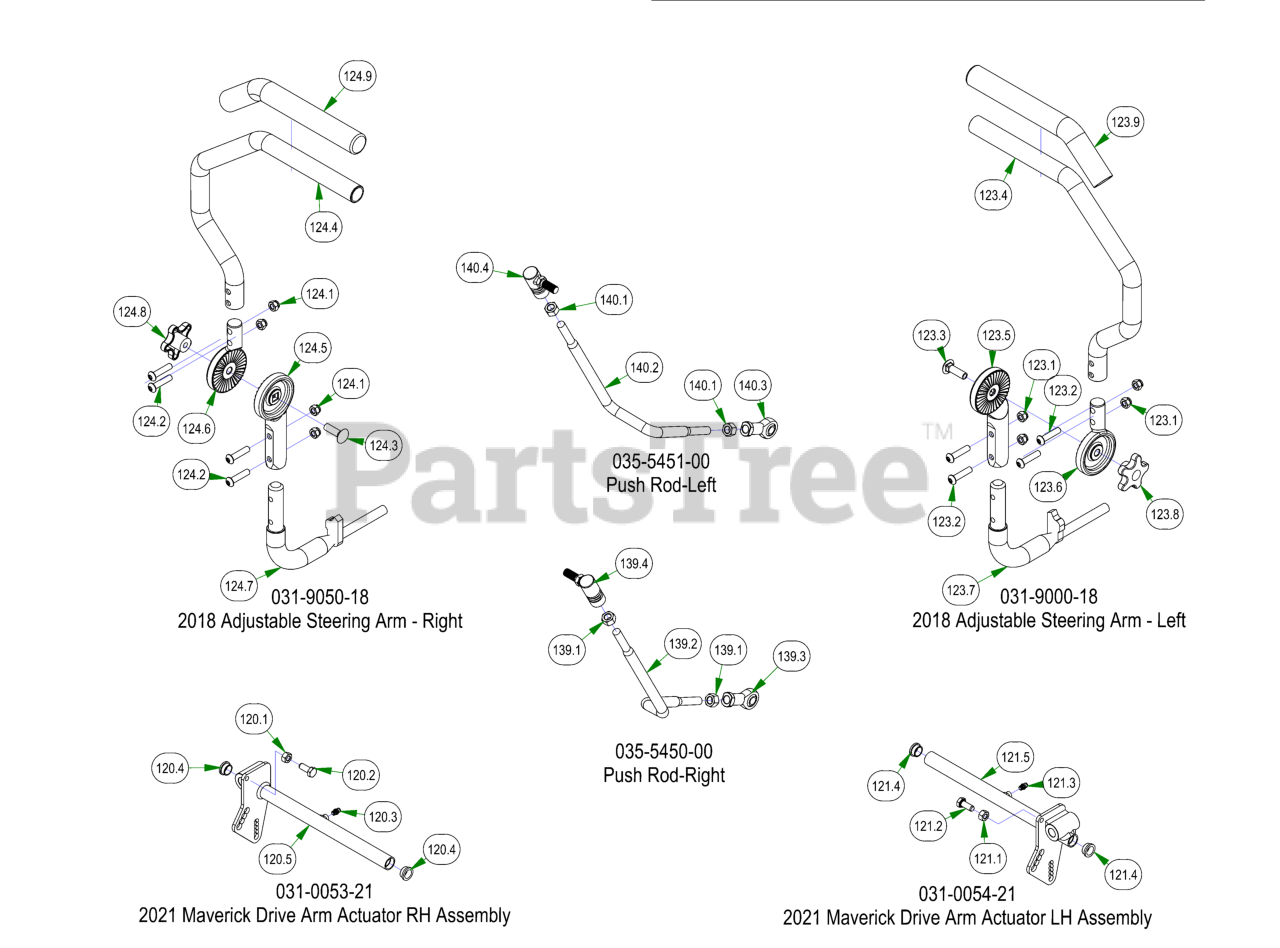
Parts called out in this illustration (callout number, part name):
120	2021 Maverick Drive Arm Actuator RH Assembly
120.1	5/16-18 HEX NUT ZINC
120.2	5/16-18 X 3/4 HEX CAP SCREW (GR.5) ZINC
120.3	1/4" Press in Grease Fitting
120.4	2019 Drive Arm Bushing
120.5	2021 Drive Actuator RH Weldment
121	2021 Maverick Drive Arm Actuator LH Assembly
121.1	5/16-18 HEX NUT ZINC
121.2	5/16-18 X 3/4 HEX CAP SCREW (GR.5) ZINC
121.3	1/4" Press in Grease Fitting
121.4	2019 Drive Arm Bushing
121.5	2021 Drive Actuator LH Weldment
123	2018 Adjustable Steering Arm - Left
123.1	5/16-18 NYL INS L/N ZC
123.2	5/16-18 UNC X 1-3/8" BHCS, TORX DRIVE, GR 5
123.3	3/8-16 X 1-1/4 CARRIAGE BOLT ZINC
123.4	Upper Tube-Adjustable Steering
123.5	2018 Lower Adjuster - Steering Arm- Left
123.6	2018 Upper Adjuster - Steering Arm- Left
123.7	Steering Arm Elbow (Left)
123.8	Black Knob for Adjustable Steering Arm
123.9	Rubber Grip
124	2018 Adjustable Steering Arm - Right
124.1	5/16-18 NYL INS L/N ZC
124.2	5/16-18 UNC X 1-3/8" BHCS, TORX DRIVE, GR 5
124.3	3/8-16 X 1-1/4 CARRIAGE BOLT ZINC
124.4	Upper Tube-Adjustable Steering
124.5	2018 Lower Adjuster - Steering Arm- Right
124.6	2018 Upper Adjuster - Steering Arm- Right
124.7	Steering Arm Elbow (Right)
124.8	Black Knob for Adjustable Steering Arm
124.9	Rubber Grip
139	Push Rod-Right
139.1	3/8" Fine Threaded Jam Nut
139.2	Push Rod RH (Rod Only)
139.3	Spherical Rod End - Outlaw
139.4	Quick Release Ball Joint
140	Push Rod-Left
140.1	3/8" Fine Threaded Jam Nut
140.2	Push Rod LH (Rod Only)
140.3	Spherical Rod End - Outlaw
140.4	Quick Release Ball Joint
